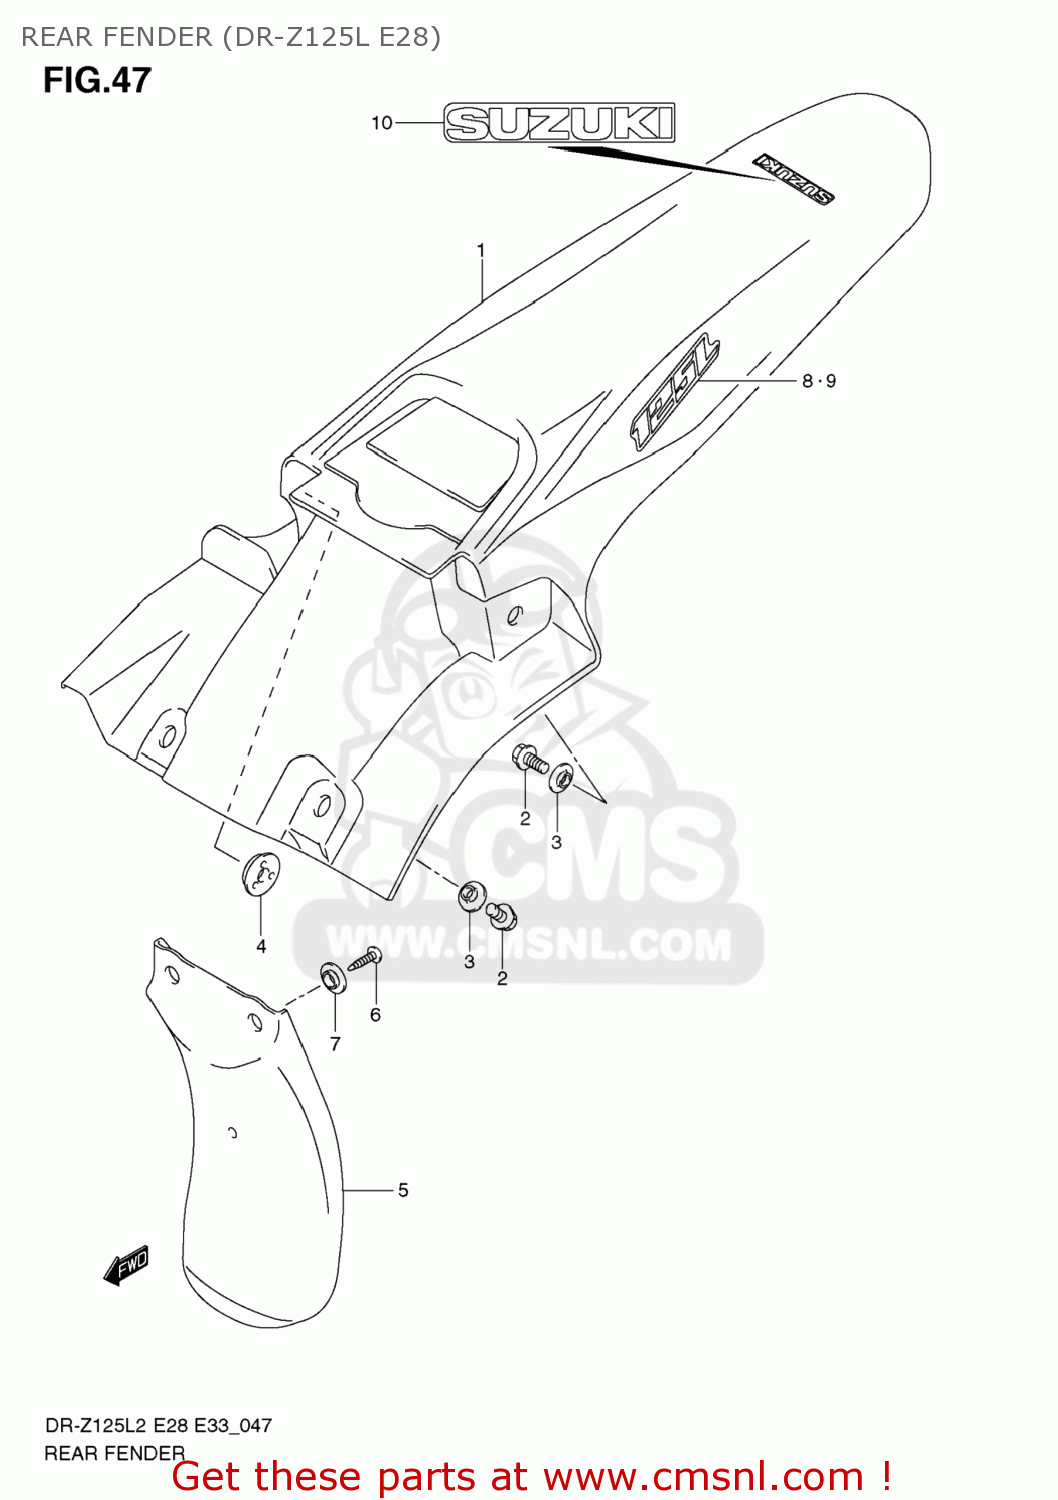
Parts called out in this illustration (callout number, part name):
1	FENDER,RR
2	BOLT(6X16)
3	WASHER
4	WASHER
5	MUDGUARD,RR FENDER FR
6	SCREW(5X16)
7	WASHER
8	EMBLEM,125L,R
9	EMBLEM,125L,L
10	EMBLEM,SUZUKI
